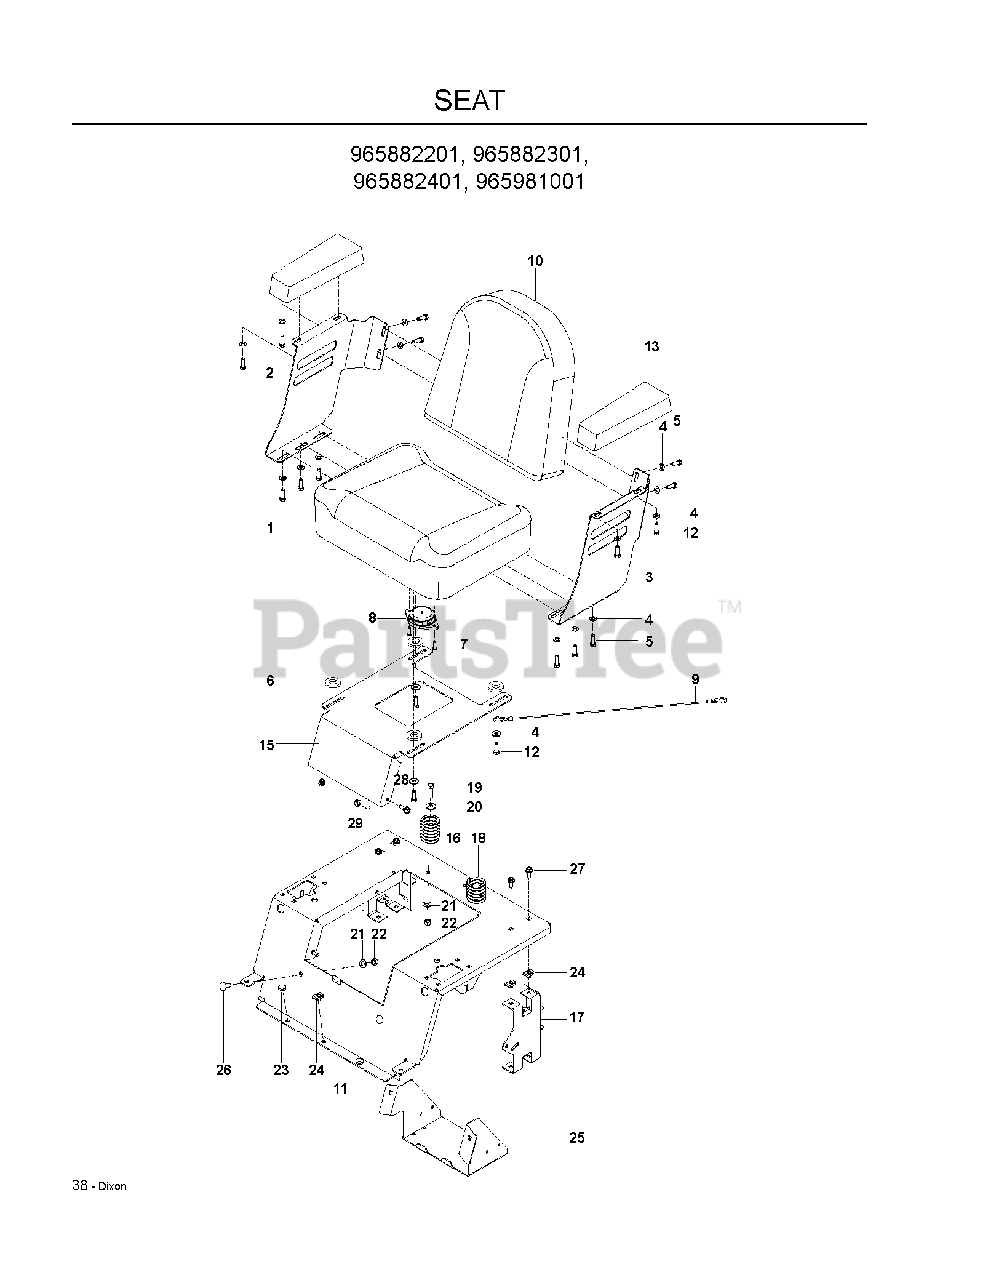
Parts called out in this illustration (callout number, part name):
1	SEAT ASSEMBLY
4	FLAT WASHER 5/16 SAE
5	5/16-18X1 HHB G5W/NY
6	WASHER NYLON
7	SCR 1/4-20X3/4 SLTD RDHD GR2ZD
8	SEAT SWITCH MILSCO
9	SEAT LANYARD
10	SEAT BACK
11	CLIP-1.06
12	CAPSCREW 5/16 X 1/1/2 HEX HEAD
13	ARMREST
14	WASHER 5/16 FLAT
15	PAN, SEAT, BLUE
16	SUPPORT, SEAT MED FLAT, BLUE
17	SUPPORT, REAR SEAT, BLACK
18	SPRING, SEAT
19	HCS 3/8C X 1 1/4 GR5
20	WASHER 3/8 FLAT
21	WASHER 3/8 SAE FLAT
22	NUT 3/8-16 NYLOC
23	GROMMET, BUMPER
24	U-CLIP 5/16-18 NUT RETAINER
25	BOX, BATTERY, BLACK
26	RHSNB 3/8C X 1
27	BOLT 5/16-18 X 3/4
28	SB 5/16-18 HEX HD GD5, BLK ZN
29	5/16-18 NYLOC FLANGE NUT
